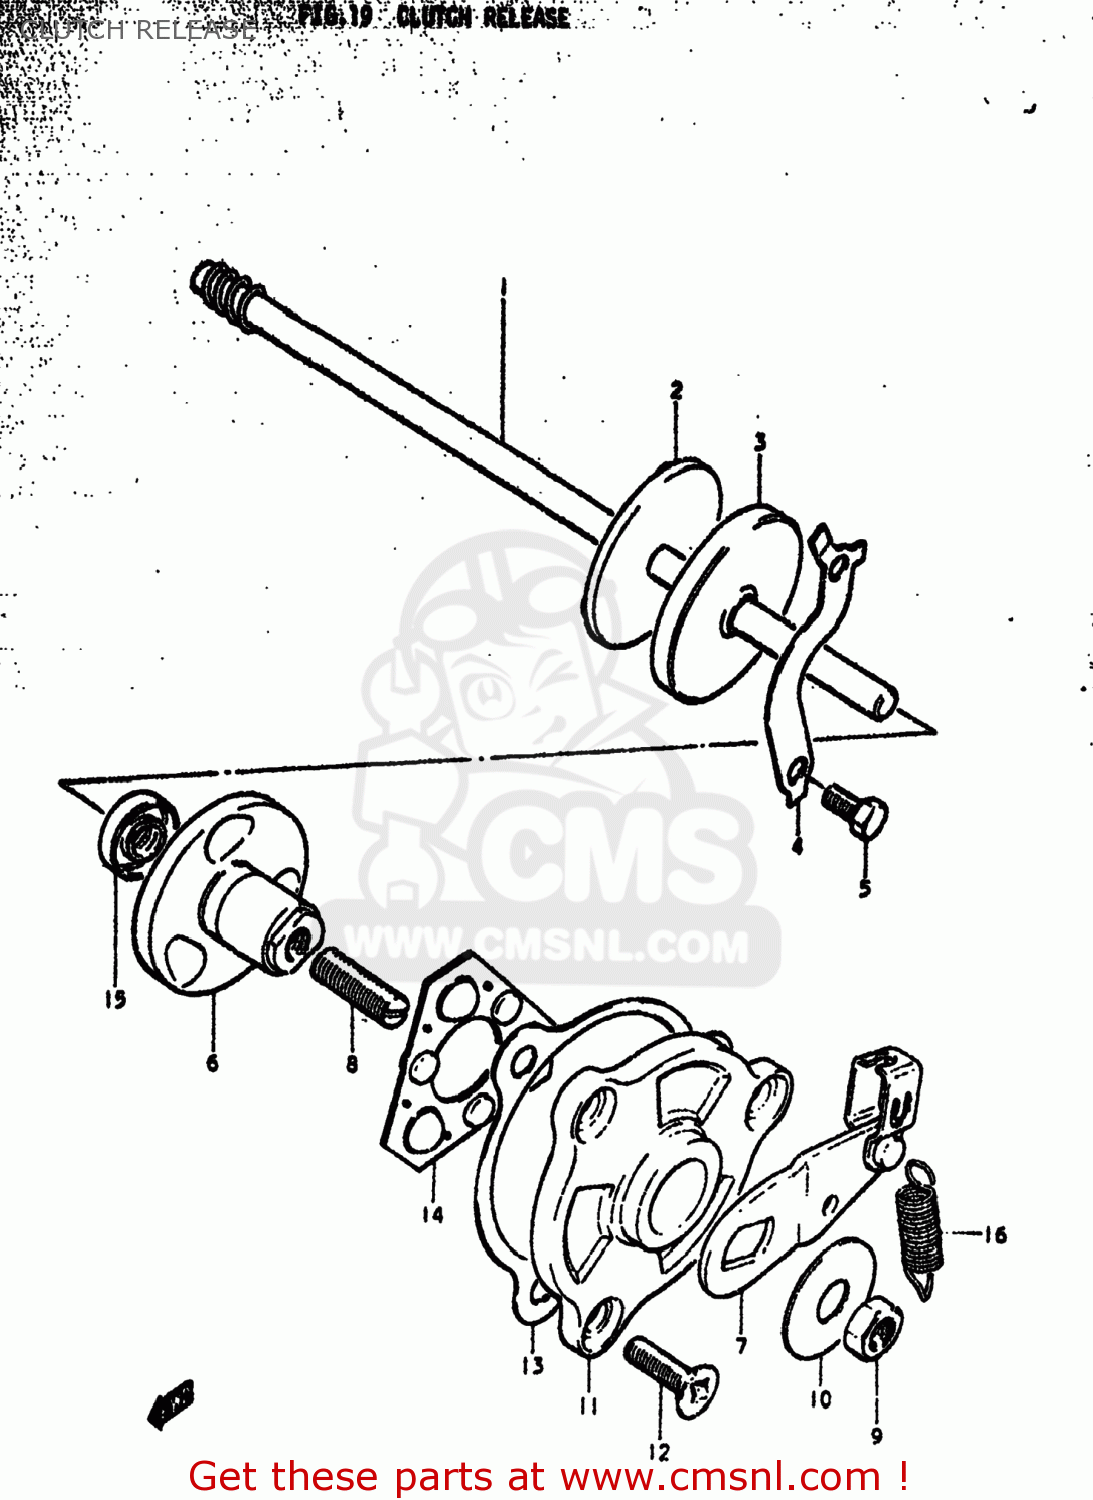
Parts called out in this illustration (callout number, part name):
1	ROD,CLUTCH PUSH
2	HOLDER,CLUTCH PUSH ROD
3	SEAL,OIL(8X47X8)
4	RETAINER,CL PUSH ROD OIL SEAL
5	BOLT
6	GUIDE,CLUTCH RELEASE,OUTER
7	ARM,CLUTCH RELEASE
8	SCREW
9	NUT 8MM
10	WASHER(8.5X26X1.2)
11	GUIDE,CLUTCH RELEASE,INNER
12	SCREW
13	GASKET,BALL GUIDE (MCA)
14	BALL,CLUTCH RELEASE
15	SEAL,OIL(8X20X7)
16	SPRING
